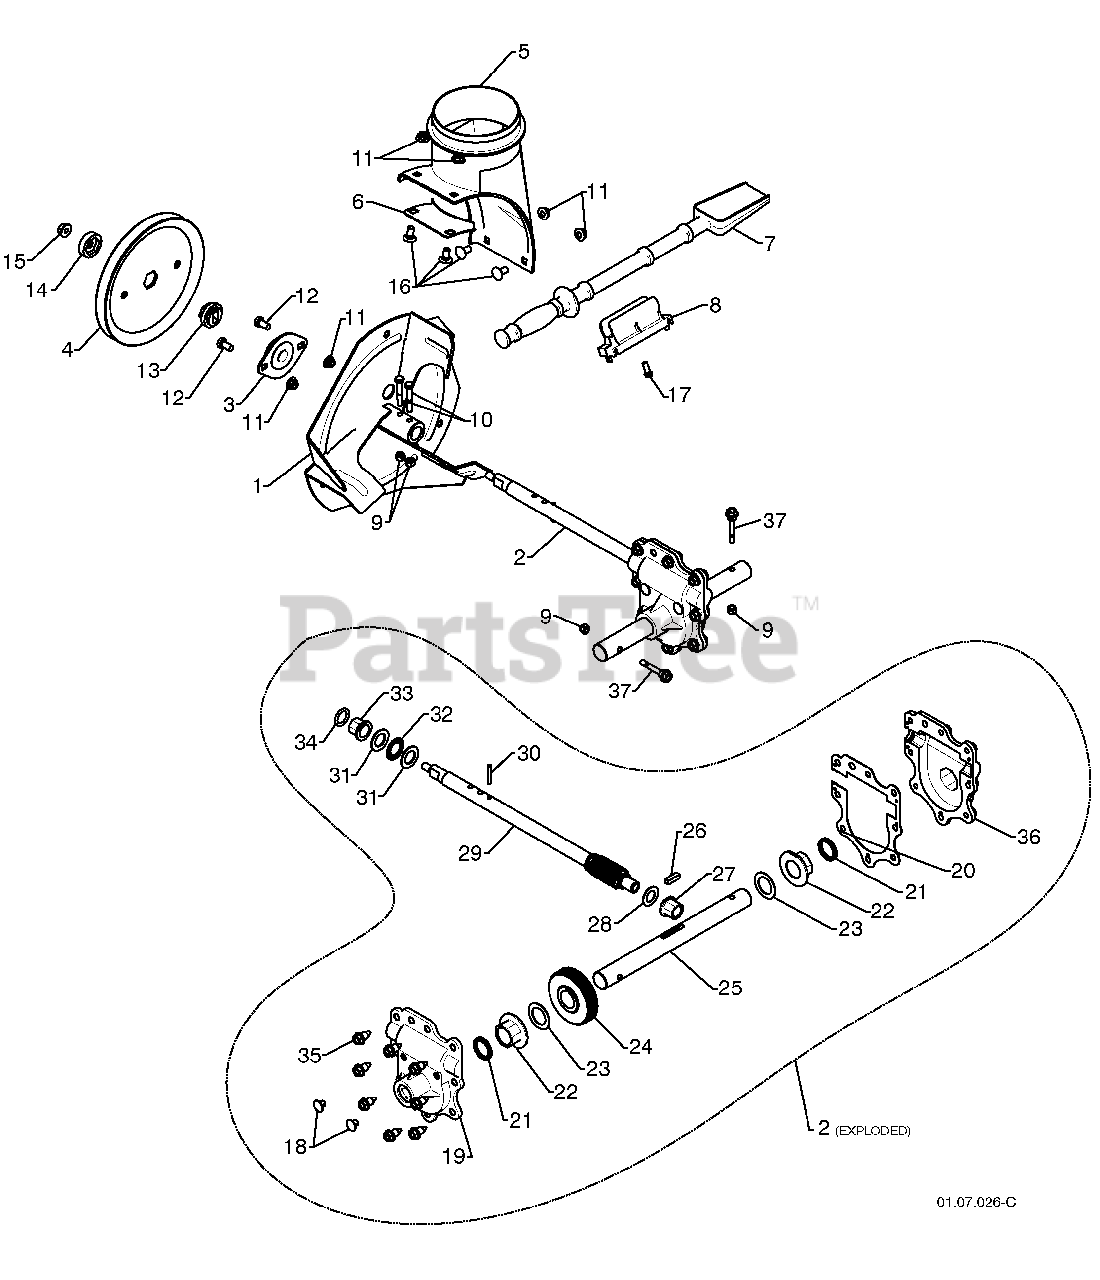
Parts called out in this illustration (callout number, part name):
1	IMPELLER
2	GEARBOX ASSEMBLY
4	IMPELLER PULLEY
5	DISCHARGE BASE
6	CORNER BRACKET
7	CLEAN OUT TOOL
9	NUT 1/4-20
10	SCREW 1/4-20 X .625
11	NUT 5/16-18
12	SCREW 5/16-18 X .625
13	IMPELLER HUB
14	IMPELLER SLEEVE
15	NUT 3/8-16
16	CARRIAGE BOLT
17	SCREW 13-16 X .625
18	PLUG
19	GEARBOX COVER RH
21	SEAL
22	BEARING
23	THRUST WASHER 1.00
24	WORM GEAR
25	AUGER SHAFT
26	SQUARE KEY
27	BEARING
28	THRUST WASHER
29	IMPELLER SHAFT
30	ROLL PIN
31	THRUST WASHER
32	THRUST BEARING
35	SCREW 5/16-18 X .750
36	GEARBOX COVER LH
37	SHEAR BOLT
